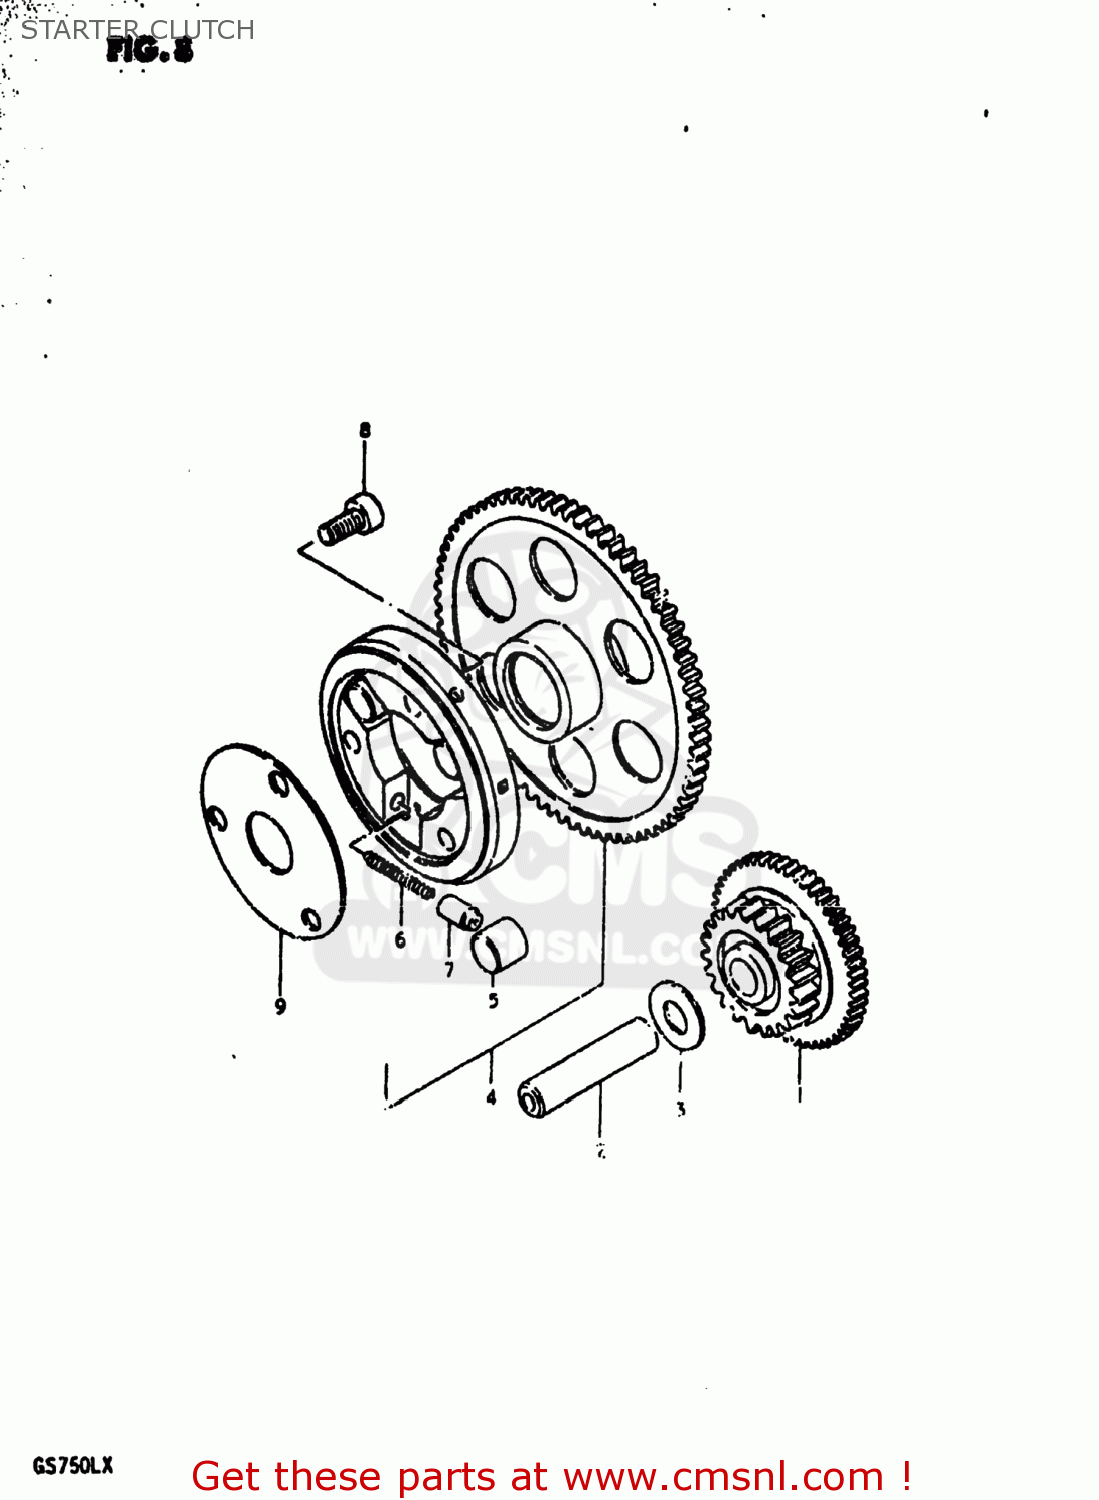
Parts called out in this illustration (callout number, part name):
1	GEAR,STARTER IDLE
2	PIN(7.4X13X56)
3	WASHER
4	CLUTCH SET,STARTER
5	ROLLER(15X13)
6	SPRING
7	PIECE,PUSH
8	BOLT
9	SHIM,STARTER CLUTCH HUB
